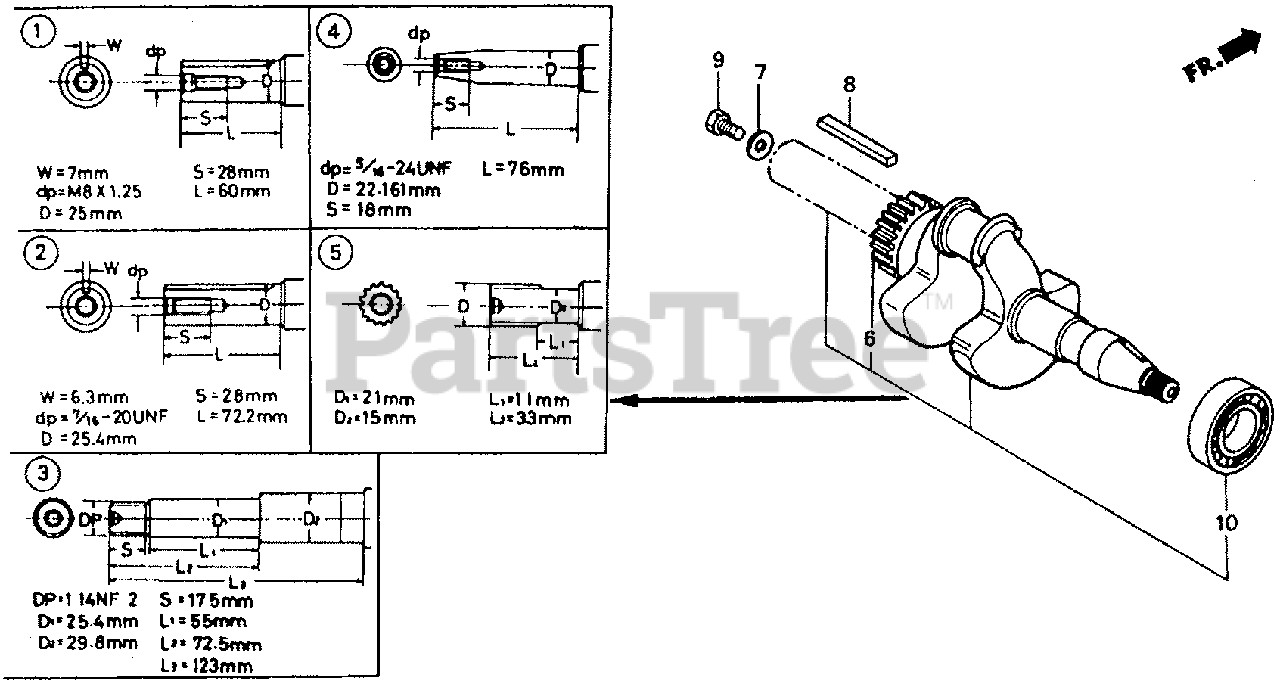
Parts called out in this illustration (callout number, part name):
2	CRANKSHAFT (Q-TYPE)
6	GEAR, TIMING
10	BEARING, RADIAL BALL (6205)
